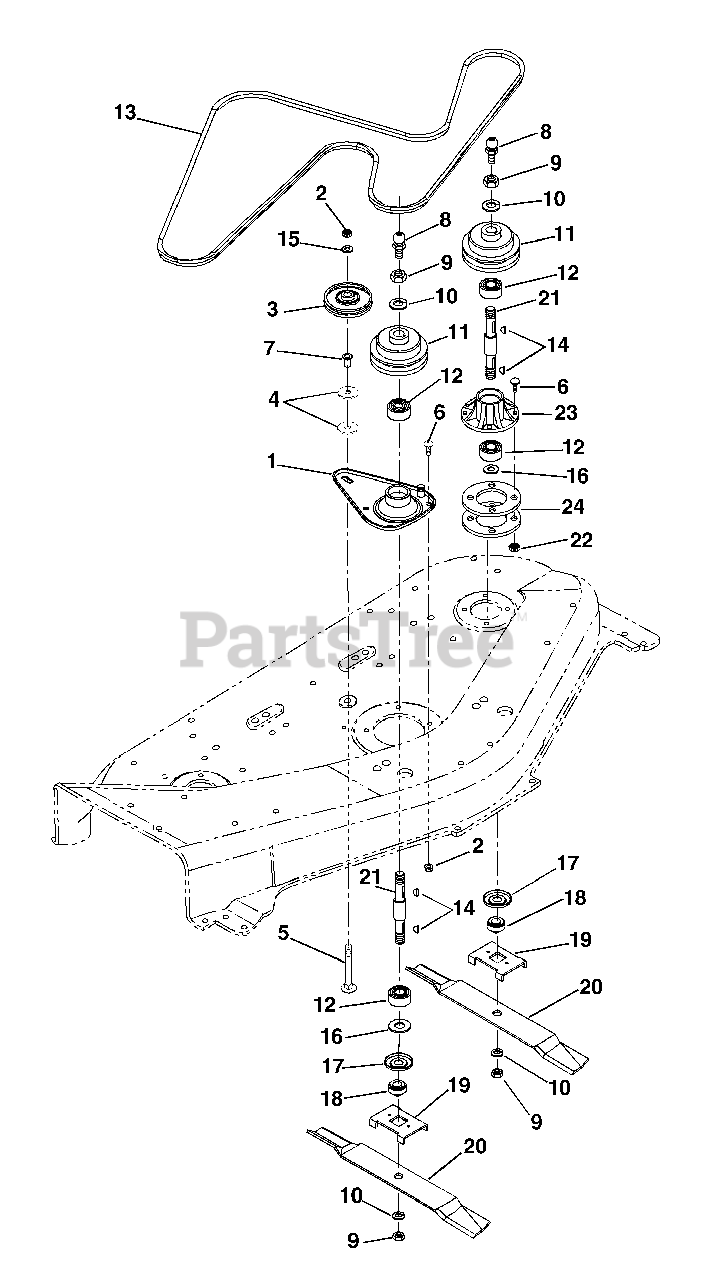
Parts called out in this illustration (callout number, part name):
1	HOUSING, SPINDLE
2	@NUT-LK-CTR .38-16 YWZC
3	IDLER, PLASTIC, 4.00 X .50 ID
4	WSHR-FL-STL .390X1.5X.125 YWZC
5	@BLT-RDHDSQNK .38-16X2.00 G2YZ
6	@BLT-RDHDSQNK .38-16X.75 G2YWZ
7	SPACER -FLANGED .390X.500X.781
8	FTG-LUBE .25-28X.256 YWZC
9	NUT-JAM .75-10 YWZC
10	@WSHR-LK .75X.188 REG YWZC
12	BRG-BALL .750X1.781X.61
13	V-BELT, HA-RAW EDGE
14	KEY-WDRF .188X.625X.25 SAE 61
15	@WSHR-FL-STL.38X.875X.083 YWZC
16	WSHR-FL-STL .754X1.000X.032 YZ
17	BEARING SLINGER
18	RETAINER HUB
19	BLADE TRAY 48
20	BLADE
21	SPINDLE SHAFT W/ZERK
22	@NUT-LK-CTR-JAM .375-16 YWZC
23	SPINDLE HOUSING
24	SPACER, SPINDLE
